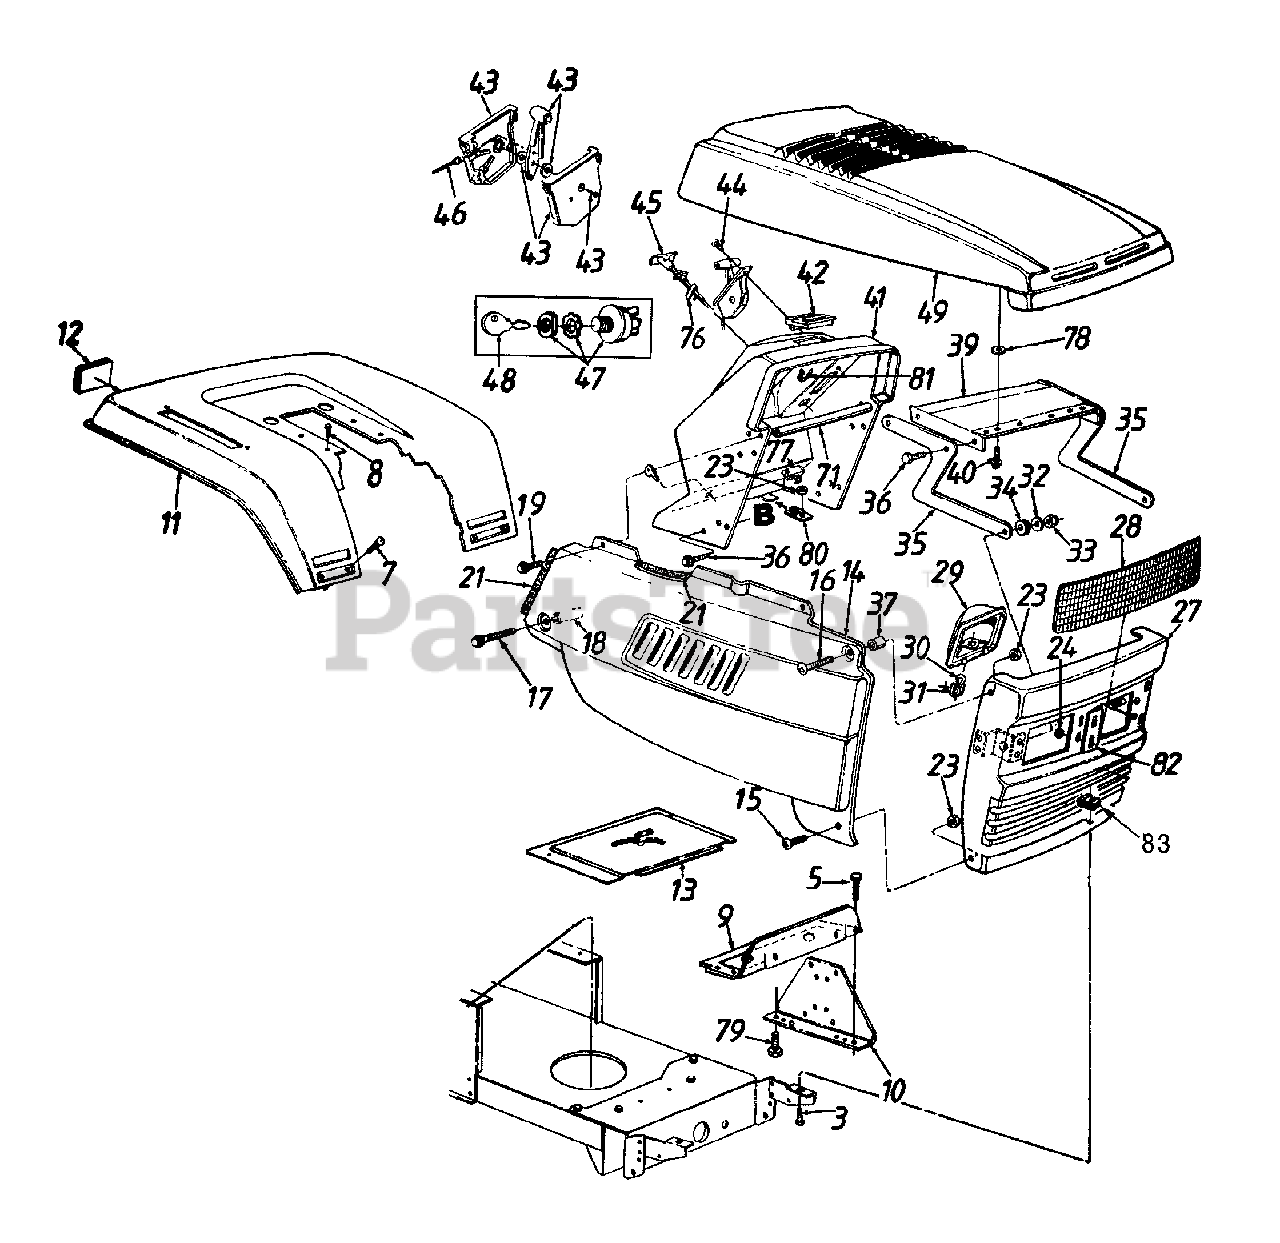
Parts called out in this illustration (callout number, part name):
3	Hex Bolt 5/16-18 x .75" Lg.
5	Hex Wash. Hd. Scr. 5/16" x .5" Lg.
7	Truss Mach. Scr. 1/4-20 x .5" Lg.
8	Hex Wash. Hd. Tap Scr.5/16 x .75" Lg.
16	Truss Mach. Scr. 1/4-20 x 1.0"
17	Hex Wash. TT-Tap Scr. 1/4-20 x
18	Spacer .26" I.D. x 1.32"
19	Hex Rolling Tap Scr. 1/4-20 x.75" Lg.
21	Trim Strip 18" Lg.
23	Hex Sems Nut 1/4-20 Thd.
24	Speed Nut 5/16" Thd.
29	Headlamp Housing
30	Headlamp
31	Twist Lock Lamp Socket
32	Bell-Wash. .345" I.D. x .88"
33	Hex L-Nut 5/16-18 Thd.
34	Rubber Washer
37	Spacer .262" I.D. x .31"
41	Dash
42	Ammeter
43	Throttle Control Box Ass'y.
44	Mach. Scr. #10 x .44" Lg.
45	Choke Control 23" Lg.
46	Throttle Control Wire 18.5" Lg.
47	Ignition Switch
48	Ignition Key
49	Hood- Red
71	Grille Support Tube
76	Choke Retainer
77	Light Switch
78	Fl-Wash. .406" I.D. x .812" O.D.
79	Hex Bolt 1/4-20 x .88" Lg.
80	Dash Fastening Tab
81	Cable Tie
82	Chrome Label
83	U-Nut 5/16-18 Thd.
